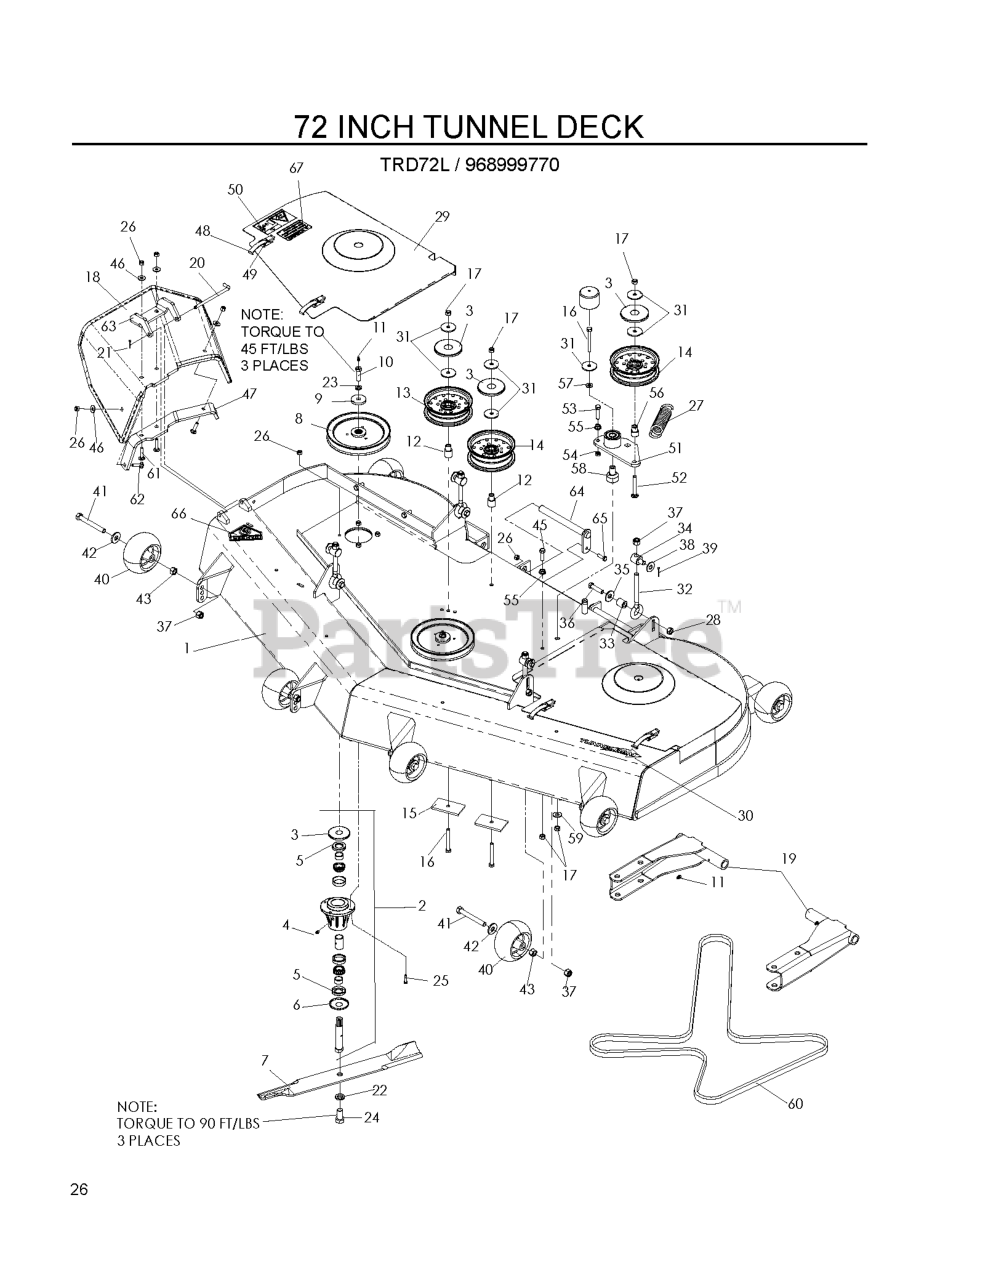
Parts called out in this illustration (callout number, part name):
1	DECK W/DECALS 72" HUS
2	HYDRAULIC KIT - LZ
3	TOP DUST CAP
4	PLUG-VENTED
5	SHAFT SEAL
6	BOTTOM DUST CAP
7	BLADE OEM - 25"
8	PULLEY, 72
9	SPINDLE WASHER
10	HCS 7/16-20 GD 8 SPEC
11	ZERK
12	IDLER BUSHING
13	IDLER PULLEY (TALL)
14	IDLER PULLEY
15	SUPPORT PLATE
16	HCS 3/8C X 3
17	NUT 3/8-16 NYLOC
18	CHUTE, RUBBER DISCHARGE 72"
19	STRUT 72, BLACK
20	PIN, CHUTE PIVOT
21	RP_COTTER PIN 1/8 X 3/4
22	LOCKWASHER 5/8
23	WASHER 7/16 LOCK
24	HCS 5/8F X 1 1/4
25	HCS 5/16C X 1 1/4
26	NUT 5/16 NYLOC
27	DECK SPRING
28	NUT 7/16C CENTERLOCK
29	72 BELT SHIELD ASM - RH
29	72 BELT SHIELD ASM LH
30	DECAL, TUNNEL RAM 8"
31	WASHER, 3/8 SPEC
35	SPRING WASHER - .50
36	HCS 7/16 - 14 X 1 3/4
37	NUT 1/2-13 HEX NYLOC ZD
38	WASHER 1/2 FLAT
39	PIN COTTER 1/8 X 1 ZD
40	GAUGE WHEEL
41	HHB, 1/2-13X4
42	WASH USS FLAT 1/2
43	NUT HEX 1/2
44	CAP, VINYL
45	HCS 3/8C X 1 1/4 GR5
46	WASHER 5/16 FLAT
47	BRACKET REINF, CHUTE
48	DRAW LATCH
49	RIVET, BLIND, 5/32 DIA
50	DECAL, EURO SEVERING
51	ARM-IDLER W/BRG
52	RHSNB 3/8-16 X 2.75
53	HCS 3/8-16 X 1-1/2
54	NUT 3/8-16 HEX JAM
55	NUT 3/8C WHIZ
56	BUSHING, IDLER
57	WASHER 3/8 SAE FLAT
58	PIVOT, BEARING
59	WASHER 3/8 FLAT
60	BELT, DECK 72"
61	RHSNB 5/16-18 X 1-1/2 GR 5 ZD
62	BOLT, CARRIAGE 5/16X1-1/4
63	PIVOT BRACKET - RUBBER CHUTE
64	PIN WELDMENT
65	HCS 5/16C X 1
66	DECAL, CPSC
67	DECAL, CAUTION
